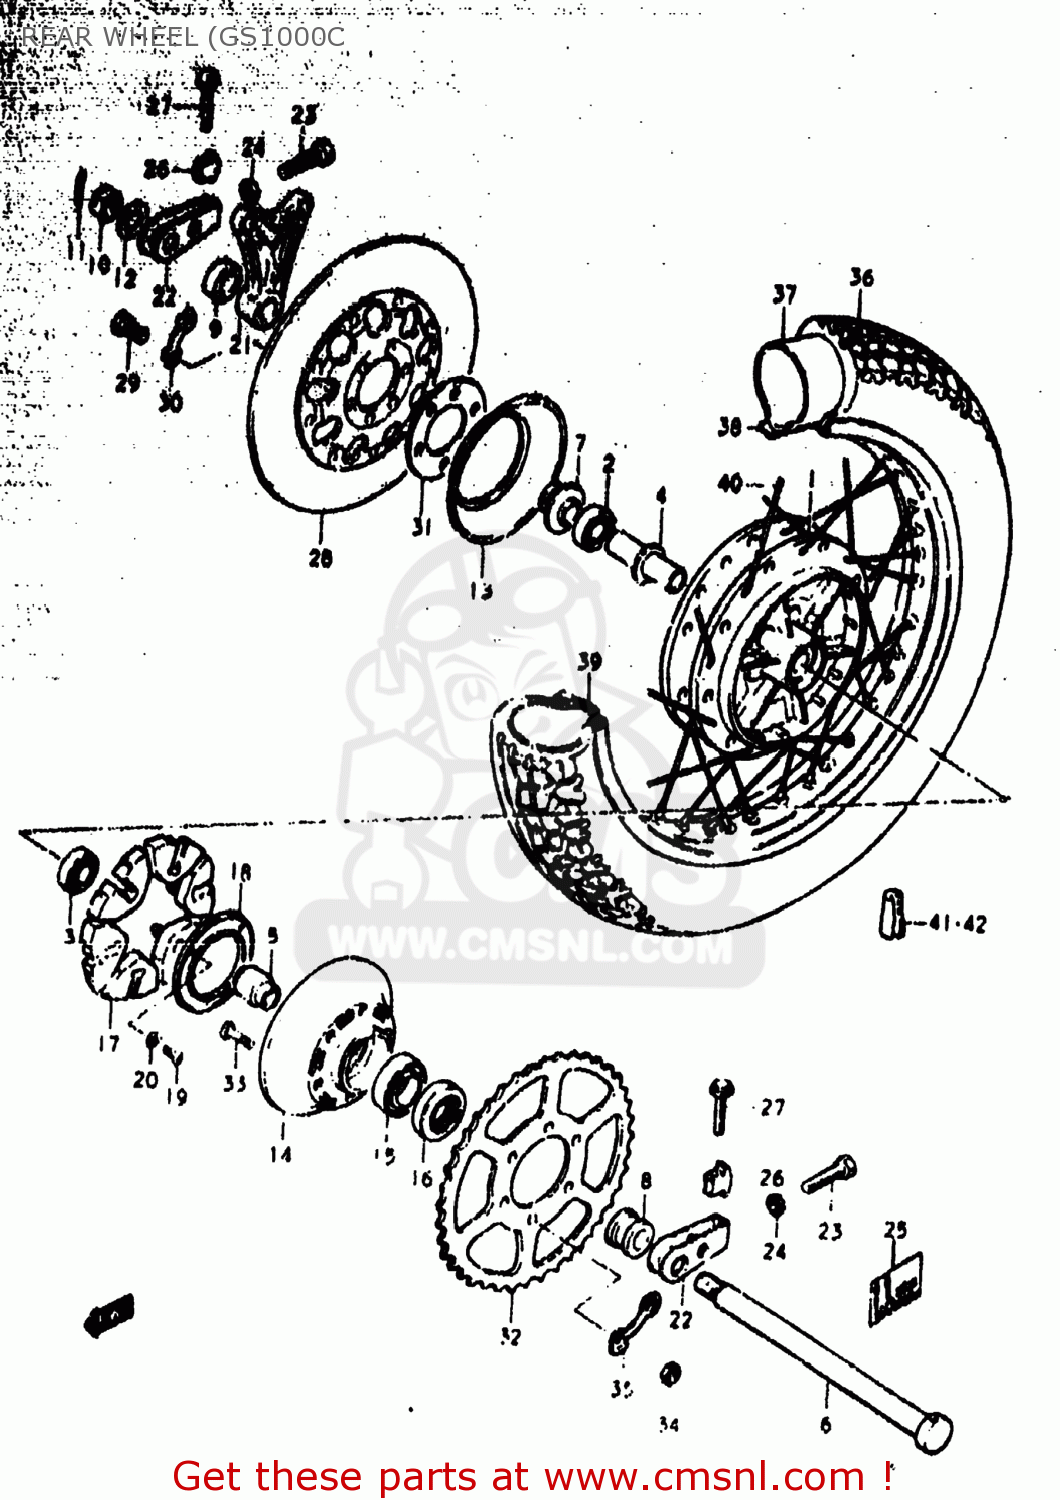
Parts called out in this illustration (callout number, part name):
1	DRUM,REAR HUB
2	BEARING
3	BEARING, LH
4	SPACER,REAR HUB BEARING
5	SPACER,REAR HUB BEARING
6	AXLE,REAR
7	SPACER,REAR AXLE,RIGHT
8	SPACER(20X33X28.3)
9	SPACER(20X38X12)
10	NUT 18MM
11	PIN,COTTER
12	WASHER(19X34X4)
13	COVER,REAR WHEEL HUB
14	DRUM,REAR SPROCKET MOUNT
15	BEARING
16	SEAL,OIL(33X62X7)
17	ABSORBER,REAR HUB SHOCK
18	PLATE,REAR HUB SHOCK ABSORBER
19	SCREW
20	LOCK WASHER
21	BRACKET,RR,CALIPER
22	ADJUSTER,CHAIN
23	BOLT
24	NUT
25	LABEL,CHAIN WEAR INDICATOR
26	SUPPORTER,CHAIN ADJUST
27	BOLT (8X40)
28	DISC,BRAKE
29	BOLT 8X40
30	WASHER
31	SHIM,BRAKE DISC
32	SPROCKET,REAR
33	BOLT
34	NUT
35	WASHER
36	TIRE
37	TUBE ASSEMBLY,WHEEL,INNER
38	PROTECTOR,WHEEL,INNER
39	RIM,REAR WHEEL
40	SPOKE SET,REAR
41	BALANCER,WHEEL (B)
42	BALANCER,WHEEL (30G)
